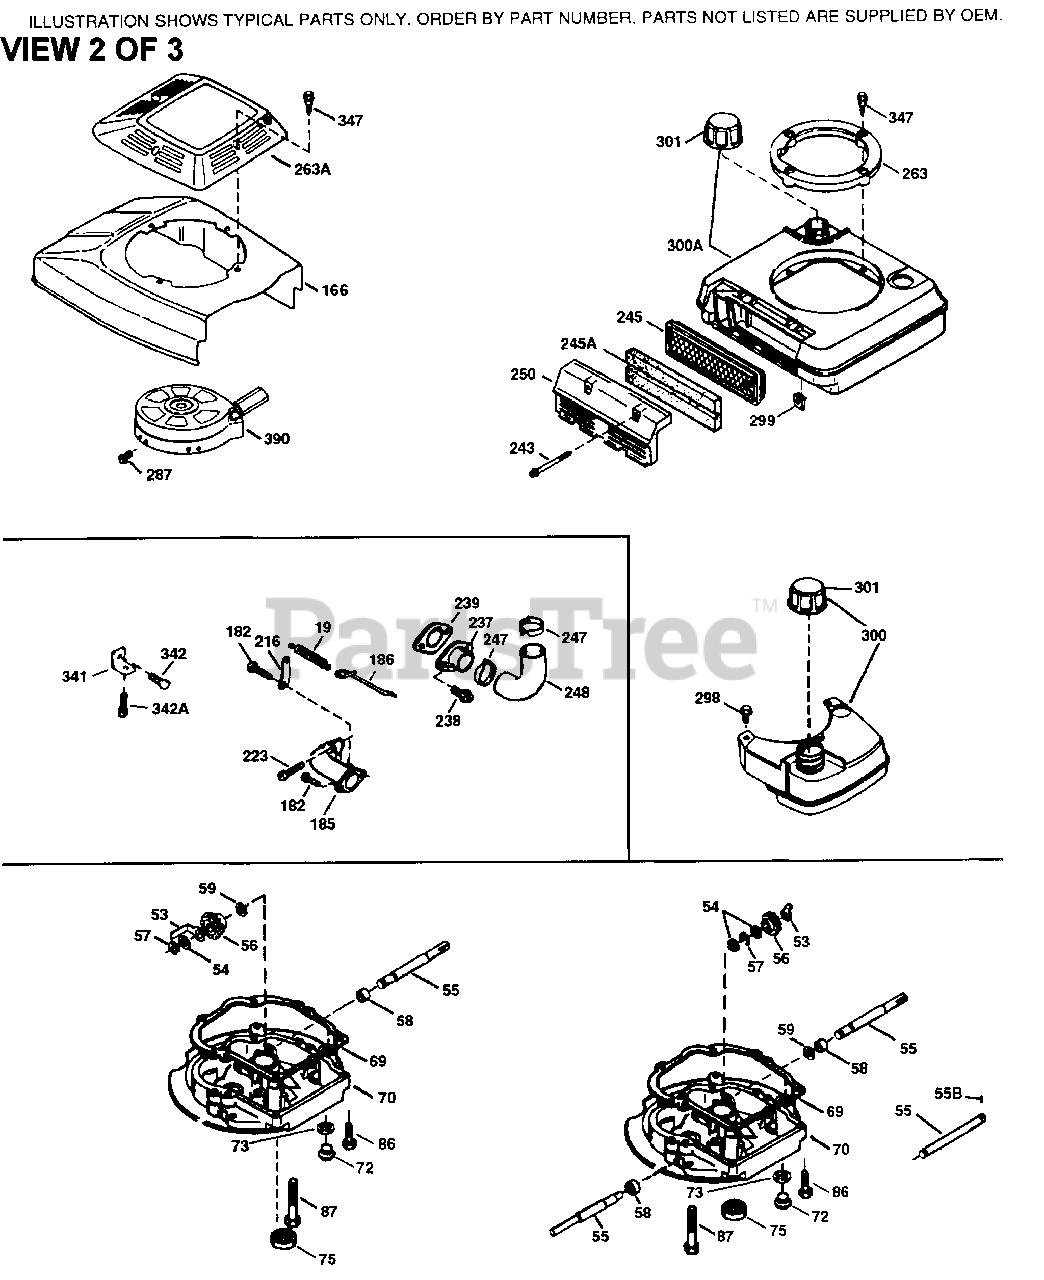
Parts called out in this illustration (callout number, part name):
19	Extension Spring
69	Mounting Flange Gasket
70	Mounting Flange (Incl. 72 thru 83)
72	Oil Drain Plug
75	Oil Seal
86	Screw, 1/4-20 x 1-1/4"
182	Screw, 1/4-28 x 7/8"
185	Intake Pipe (Incl. 224)
186	Governor Link
223	Screw, 1/4-20 x 1"
238	Screw, 10-32 x 5/8"
239	* Air Cleaner Gasket
245	Air Filter (Poly) (also available in Packaged Part #740023B)
250	Air Cleaner Cover
287	Screw, 8-32 x 21/64"
298	Screw, 10-32 x 35/64"
300	Fuel Tank (Incl. 292 & 301)
301	Fuel Cap (Red 1-1/2" ID) also availab le in Packaged Part #740005B
390	Rewind Starter
